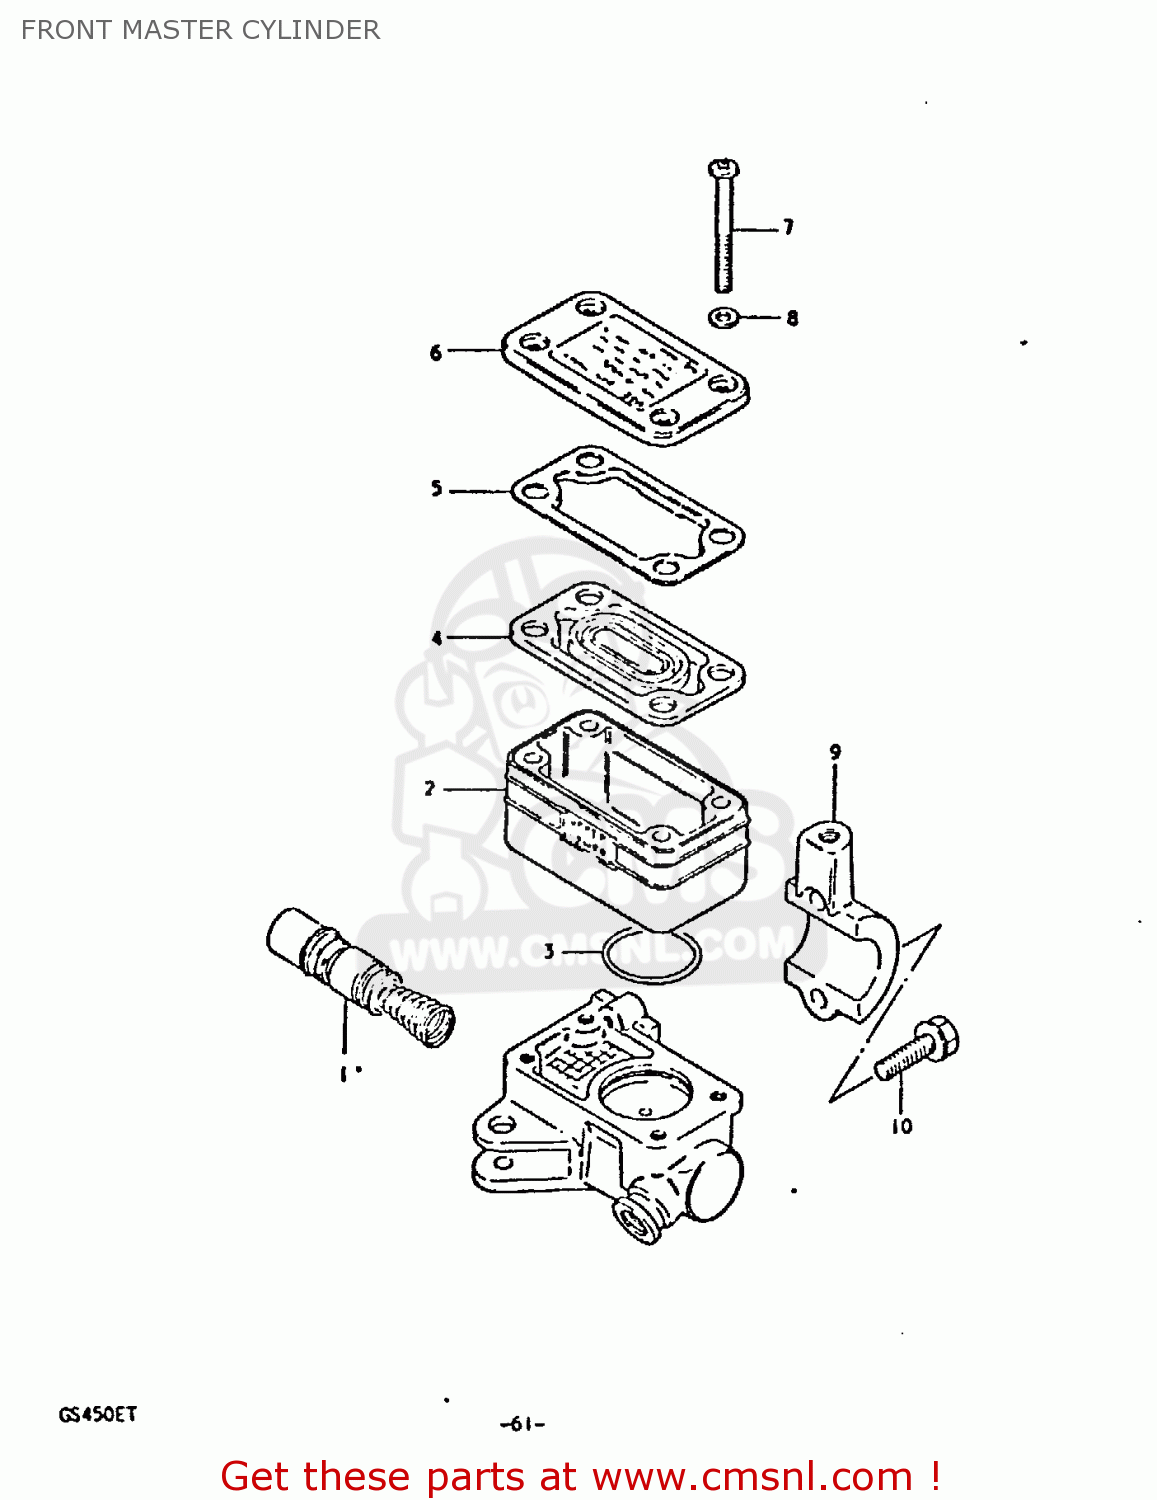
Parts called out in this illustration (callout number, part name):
1	CUP SET,MASTER CYLINDER
2	RESERVOIR
3	O RING
4	DIAPHRAGM
5	PLATE,DIAPHRAGM
6	CAP
7	SCREW
8	WASHER
9	HOLDER
10	BOLT,MASTER CYLINDER H
